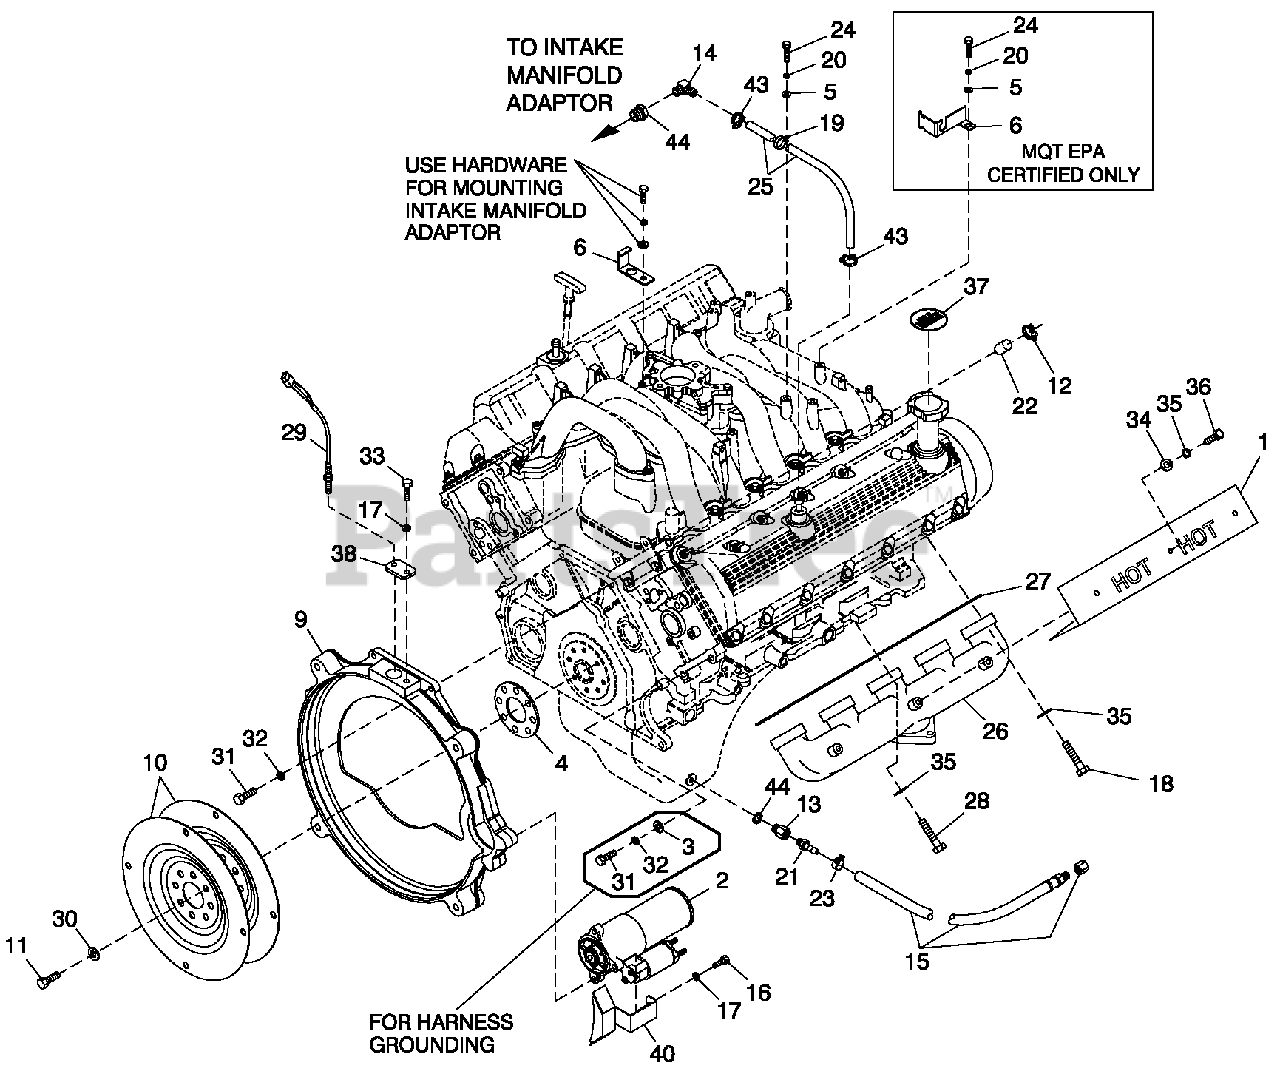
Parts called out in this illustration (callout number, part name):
1	HEAT SHIELD EXHAUST
2	STARTER MOTOR FORD V-10 ENGINE
3	WASHER FLAT 3/8-M10 ZINC
4	SPACER FLEXPLATE 5.4L/6.8L (1800 RPM UNITS ONLY)
5	WASHER FLAT 1/4-M6 ZINC
6	BRACKET SIGNAL CONDITIONER
8	WASHER NYLON .565
9	ENGINE ADAPTER 5.4L/6.8L
10	FLEX PLATE 2 POLE (1800 RPM UNITS ONLY)
11	SCREW HHC M10-1.0 X 25 G10.9
12	CLAM P HOSE #10 .56 - 1.06 (1800 RPM UNITS ONLY)
13	ADAPTER M14-1.50X 3/8 N PT
14	BARBED EL 90 3/8N PTX5/8
15	HOSE DRAIN ASSY 28"
16	SCREW HHC M8-1.25X3 0 G8.8
17	WASHER LOCK M8-5/16
18	SCREW SHC M8-1.25X 35 SS
19	CLAM P VINYL .7 5X .3 4 3Z
20	WASHER LOCK M6-1/4
21	BARBED STR 3/8 N PTX3/8
22	CA P HOSE (1800 RPM UNITS ONLY)
23	HOSE CLAM P BAND 5/8"
24	SCREW HHC M6-1.0X 16 G8.8
25	HOSE COOL 5/8" ID 250#WP (14")
26	EXH MANIFOLD MACH 6.8L V-10
27	GASKET EXHAUST MANIFOLD
28	SCREW HHC M8-1.25 X 35 SS G8.8
29	ASSY MAG PICKUP (3/8-24 MALE)
30	WASHER FLAT .43X1.00
31	SCREW SHC M10-1.5 X 25 G12.9
32	WASHER LOCK M10
33	SCREW HHC M8-1.25X2 0 G8.8
34	WASHER FLAT M8 SS
35	WASHER LOCK M8 SSTL
36	SCREW HHC 5/16-18 X 1/2 SSTL
37	DECAL REFER TO OWNERS MANUAL
38	PLATE MAG PICK-U P ADAPTOR
40	COVER STARTER 5.4 & 6.8 FORD CPL
43	CLAM P HOSE #10 .56-1.06
44	ADAPTOR 1/4" N PT TO 3/8" N PT
